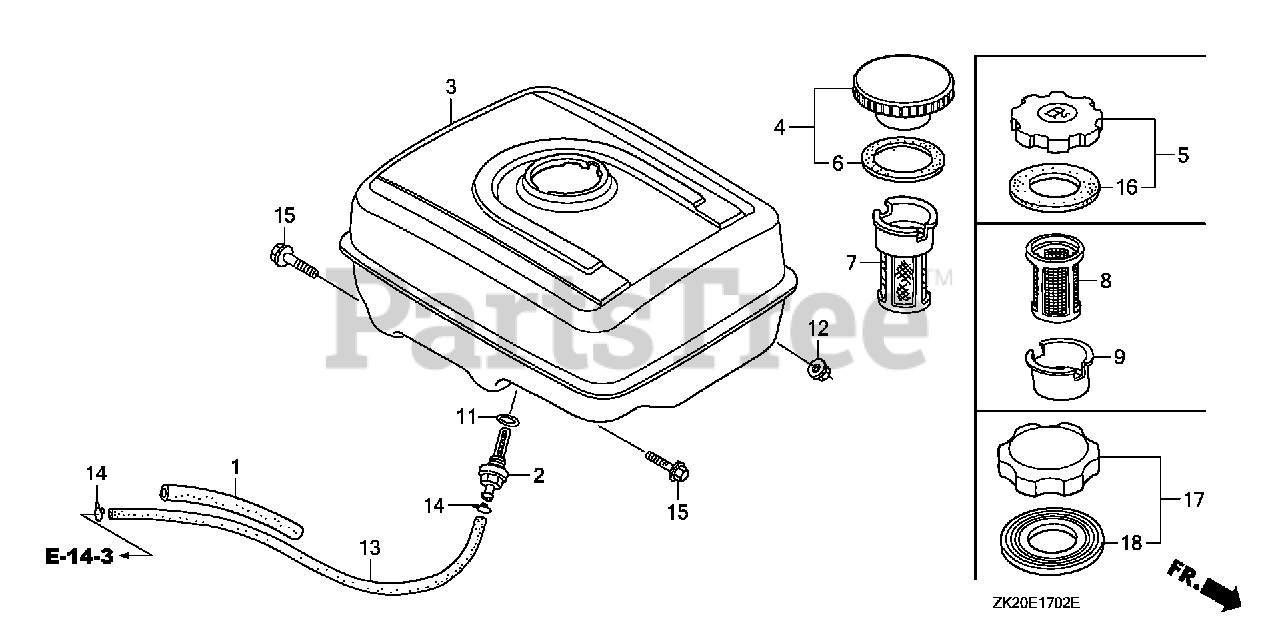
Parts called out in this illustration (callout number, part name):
1	RUBBER, SUPPORTER (107MM)
2	JOINT, FUEL TANK
3	TANK, FUEL *NH31* (MCKINLEY WHITE)
4	CAP, FUEL FILLER (CHROME PLATED)
4	CAP, FUEL FILLER
5	CAP, FUEL FILLER (BLACK)
6	GASKET, FUEL FILLER CAP (39X58X3)
7	FILTER, FUEL
8	FILTER, FUEL
9	HOLDER, FUEL FILTER
11	O-RING (14MM) (ARAI)
11	O-RING (14MM) (NOK)
12	NUT, FLANGE (8MM)
13	BULK HOSE, FUEL (4.5X3000) (4.5X222)
14	CLIP, TUBE (B8)
15	BOLT, FLANGE (8X25)
16	GASKET, FUEL FILLER CAP (39X58X3)
